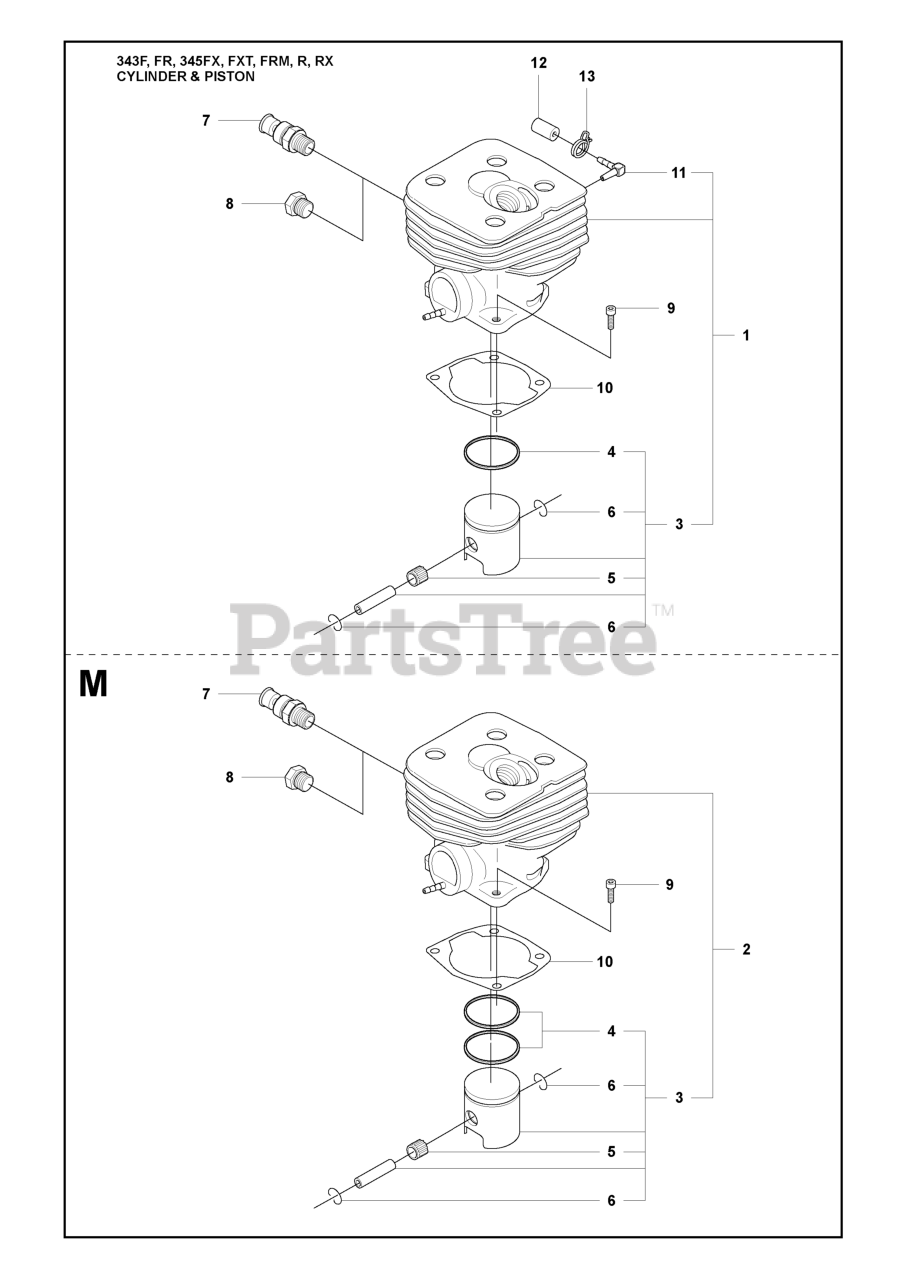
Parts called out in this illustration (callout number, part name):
1	CYLINDER
2	CYLINDER ASSY
3	PISTON ASSEMBLY
3	RP PISTON ASSY
4	PISTON RING
5	SUPPORT BUSHING
6	LOCKING RING
7	DECOMPRESSION VALVE
8	CYLINDER PLUG
9	SCREW MC6S 5X20
10	GASKET
11	NIPPLE
12	PROTECTIVE CAP
13	CLAMP
